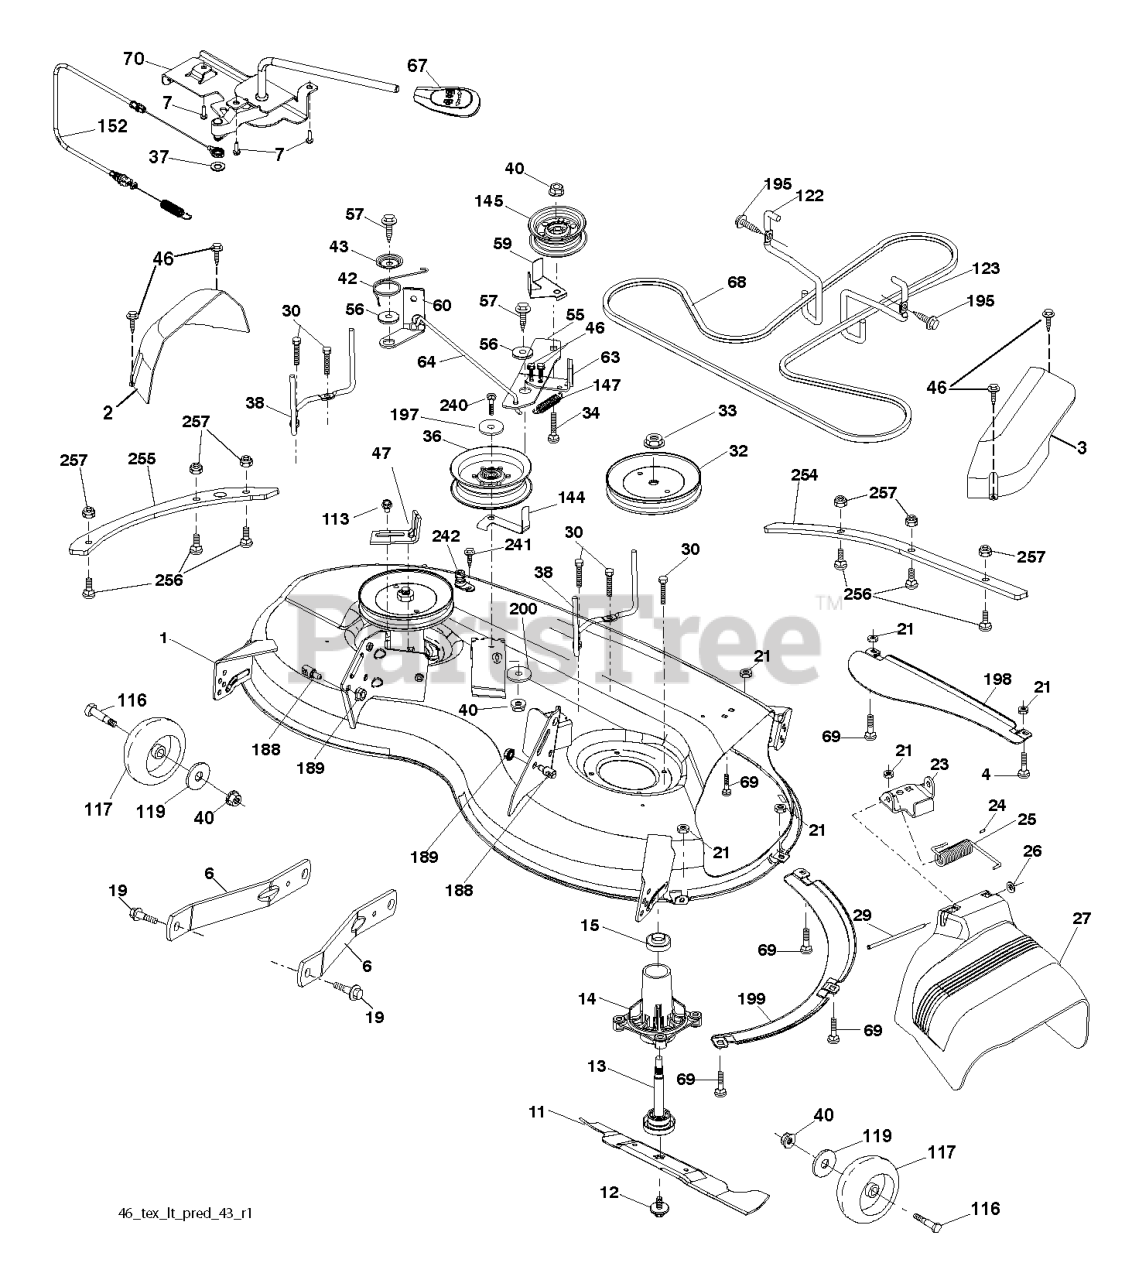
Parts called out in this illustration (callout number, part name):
1	DECK.WELDMENT.46.2GA.WHLS.GRAY
2	COVER.MANDREL.RH.46"
3	COVER.MANDREL.LH.46"
4	BOLT
6	ARM.SUSPENSION.MOWER.R
7	SCREW.#10 X 0.750.BOS
11	BLADE.MOWER.46".HI.LIFT
12	SCREW.SEMS.7/16-20X1.HEX.HEAD
13	SHAFT ASM.MNDRL.N/GREASEABLE
14	RP.HOUSING.MANDREL.4PT.
19	BOLT.SHOULDER
21	LOCKNUT
23	BRKT.DEFLECTOR.38"2005+
24	CAP-SLEEVE LT
25	SPRING.TORSION.DEFLECT
26	NUT PUSH M
27	SHIELD.DEFLECTOR.MOWER.46"BLAC
29	ROD.HINGE
30	SCREW, WASHER HEAD
32	PULLEY.MANDREL.5.438.PD
33	NUT.FLANGE.LOCK.TOP
34	BOLT.3/8-16X1.50
36	PULLEY.IDLER.2006
37	WASHER
38	KEEPER.BELT.MANDREL.PULLEY
40	NUT LOCK FLG 3/8-16 UNC
42	SPRING.TORSION.BRAKE
43	SRPING.TORSION.RETAINE
46	SCREW.1/4-20X5/8
47	BRKT.CLUTCH.CABLE
55	IDLER.ARM
56	SPACER.RETAINER
57	SCREW 3/8-16X1
59	GUARD, BELT
60	ARM BRAKE MOWER RH 38"
63	ARM BRAKE MOWER
64	LINKAGE BRAKE
67	HANDLE.CLUTCH.CABLE.LT
68	V-BELT
69	BOLT
70	CLUTCH.ASM.MANUAL.YT.PREDATORQ
113	BOLT.5/16HEX.WHS.HD
116	BOLT.SHOULDER.3/8-16X3-5/8.
117	RP WHEEL. GUAGE RALLY
119	WASHER
122	KEEPER BELT ENGINE LH
123	KEEPER BELT RH
144	KEEPER.BELT.MOWER
145	PULLEY.IDLER.48"PRIMARY
147	SPRING RETURN
152	CABLE.MECHANICAL.CLUTCH
188	STUD.FASTNER.W/ANTI-ROTATE
189	NUT LOCK HEX FLANGE 5/16-18
195	SCREW, 3/8-16X3/4
197	WASHER
198	BAFFLE CENTER FRONT
199	BAFFLE FRONT RH
200	WASHER.13/32 X 1 X 1/2.11GUARD
240	BOLT-HEX EAK
241	SCREW.TT.#10-32X.5.3/8.FLANGE
242	PORT.WASHOUT
254	PLATE.RNFRCMENT.46.FRONT X431
255	PLATE.RFORCRMRNT.46.SIDE X431
256	SCREW.BUTTONHEAD.1/4-20X1
257	NUT T
